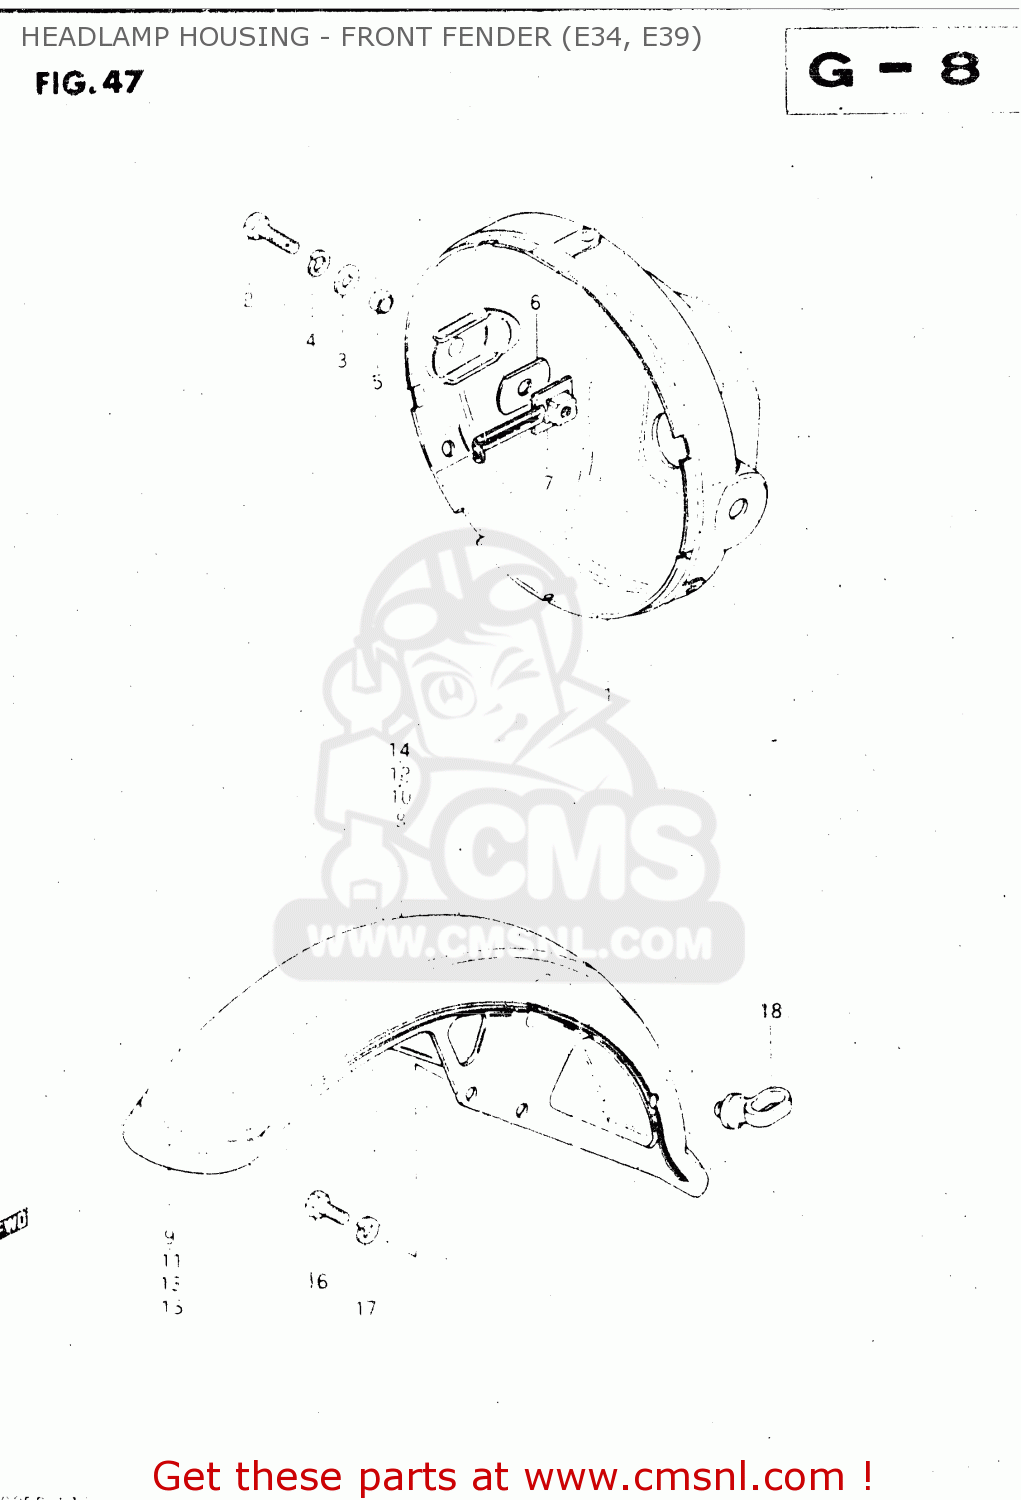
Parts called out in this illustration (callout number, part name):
1	HOUSING,HEADLAMP
2	BOLT
3	WASHER
4	LOCK WASHER
5	SPACER (8.8X12X7)
6	CUSHION
7	PLATE,HEADLAMP HOUSING
8	FENDER, FRONT (RED)
9	TAPE
10	FENDER, FRONT (BLUE)
11	TAPE
12	FENDER,FRONT
13	TAPE
14	FENDER, FRONT (BLUE)
15	TAPE
16	BOLT
17	LOCK WASHER
18	GUIDE,CABLE
